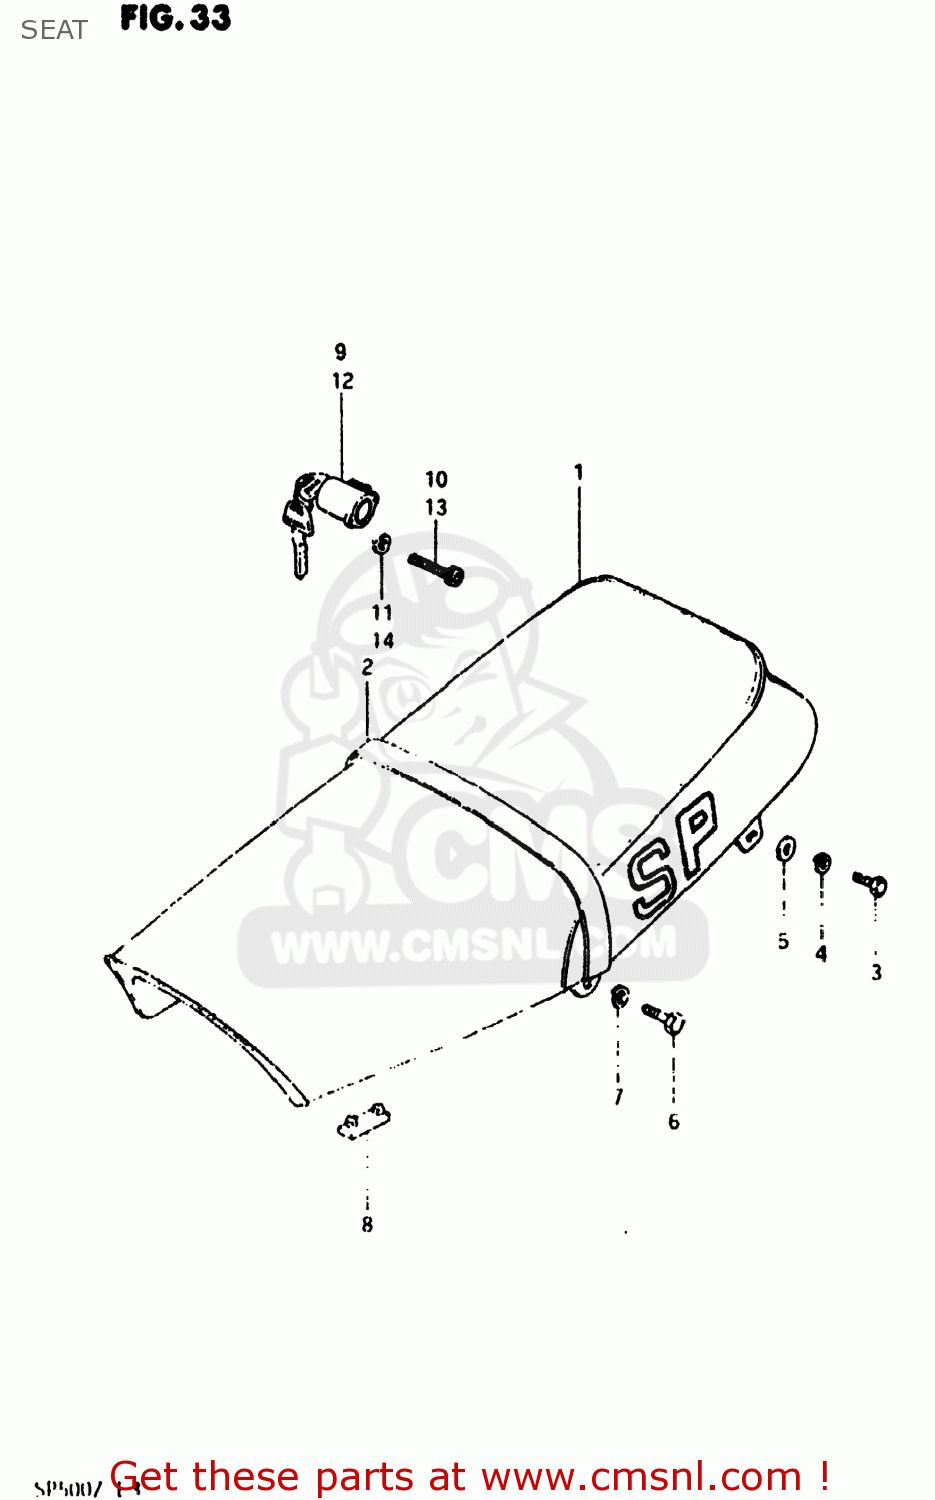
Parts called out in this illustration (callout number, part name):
1	SEAT ASSEMBLY
2	BAND,SEAT
3	BOLT
4	WASHER,LOCK,8.
5	WASHER
6	BOLT
7	LOCK WASHER
8	CUSHION
9	LOCK ASSEMBLY,HELMET
10	SCREW
11	LOCK WASHER
12	LOCK SET,HELMET
13	SCREW
14	LOCK WASHER
